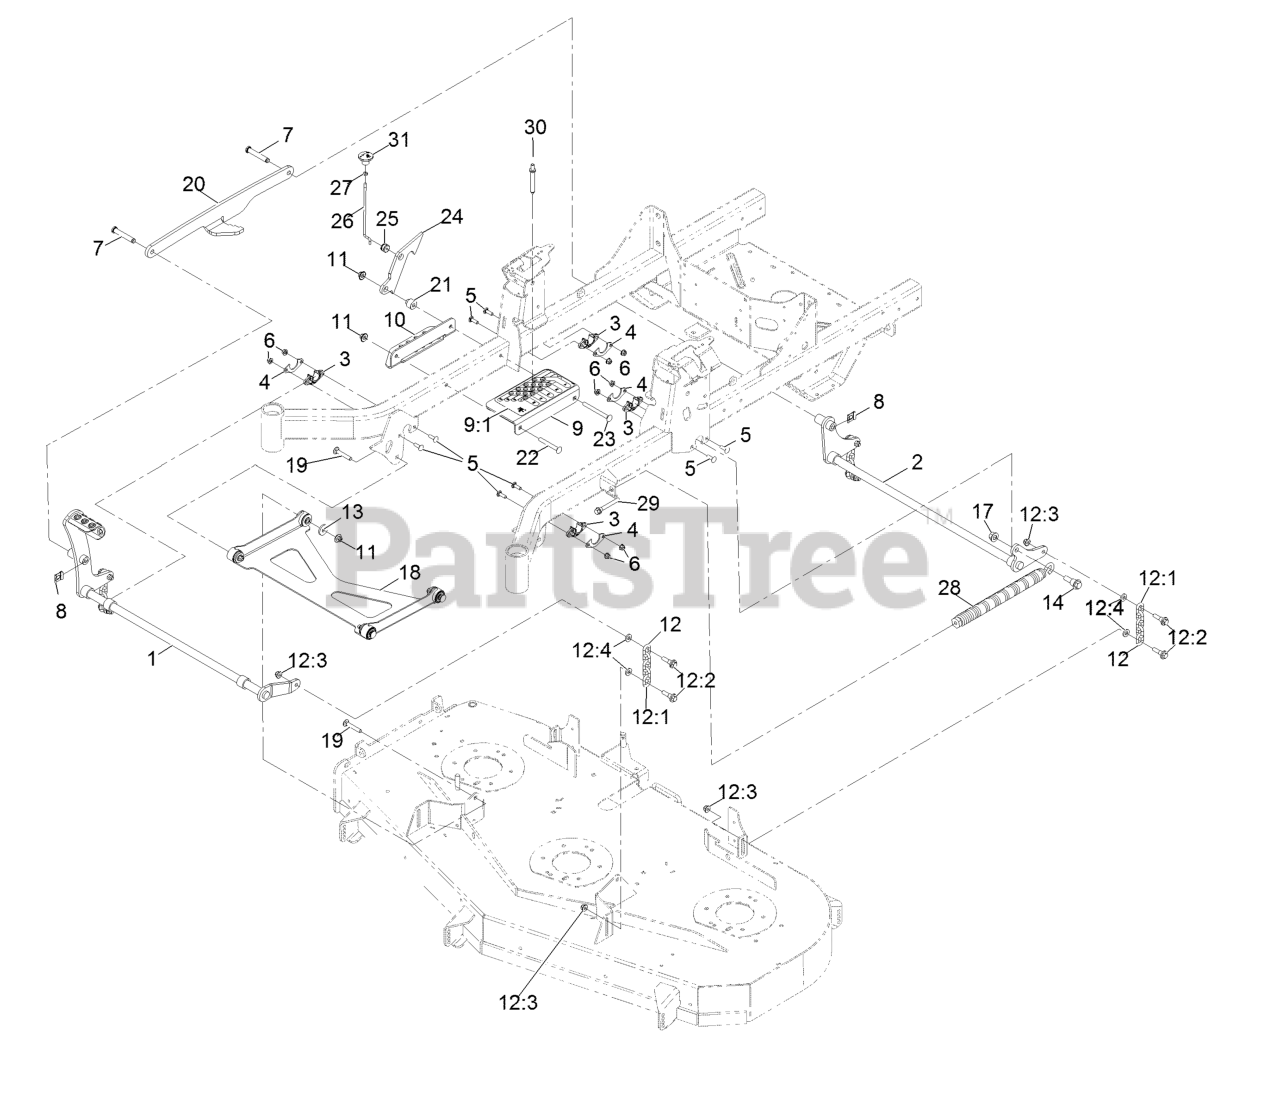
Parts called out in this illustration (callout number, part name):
1	Shaft-Lift, Deck
2	Shaft-Lift, Deck (Rear)
3	Bushing-Flange
4	Gusset-Lift, Deck
5	Bolt-Carriage 5/16-18 X 1 Sp
6	Nut-Nyloc 5/16-18 Flg
7	Pin-Clevis
8	Clip-Pin
9	Bracket ASM
9:1	Decal-HOC
10	Angle-HOC, Lower
11	Nut-Nyloc 3/8-16 Flg
12	Deck Chain ASM
12:1	Chain-Lift, Deck
12:2	Bolt-Shoulder
12:3	Nut-Nyloc 3/8-16 Flg
14	Screw-Shoulder HHF 1/2-13 X 1.12
17	Nut-Lock 1/2-13
18	Deck Strut ASM
19	Bolt-Carriage 3/8-16 X 2 1/4
20	Link-Lift
21	Spacer-Stepped
22	Bolt-Carriage 3/8-16 X 3
23	Screw-CARR
24	Plate-Lock, Transport
25	Grommet
26	Rod-Lock, Transport
27	Nut-Jam 1/4-20
28	Sub-Contract Bom
28	Spring-Extension
29	Screw-Shcs 3/8-16 X 2.212
30	Pin-HOC
